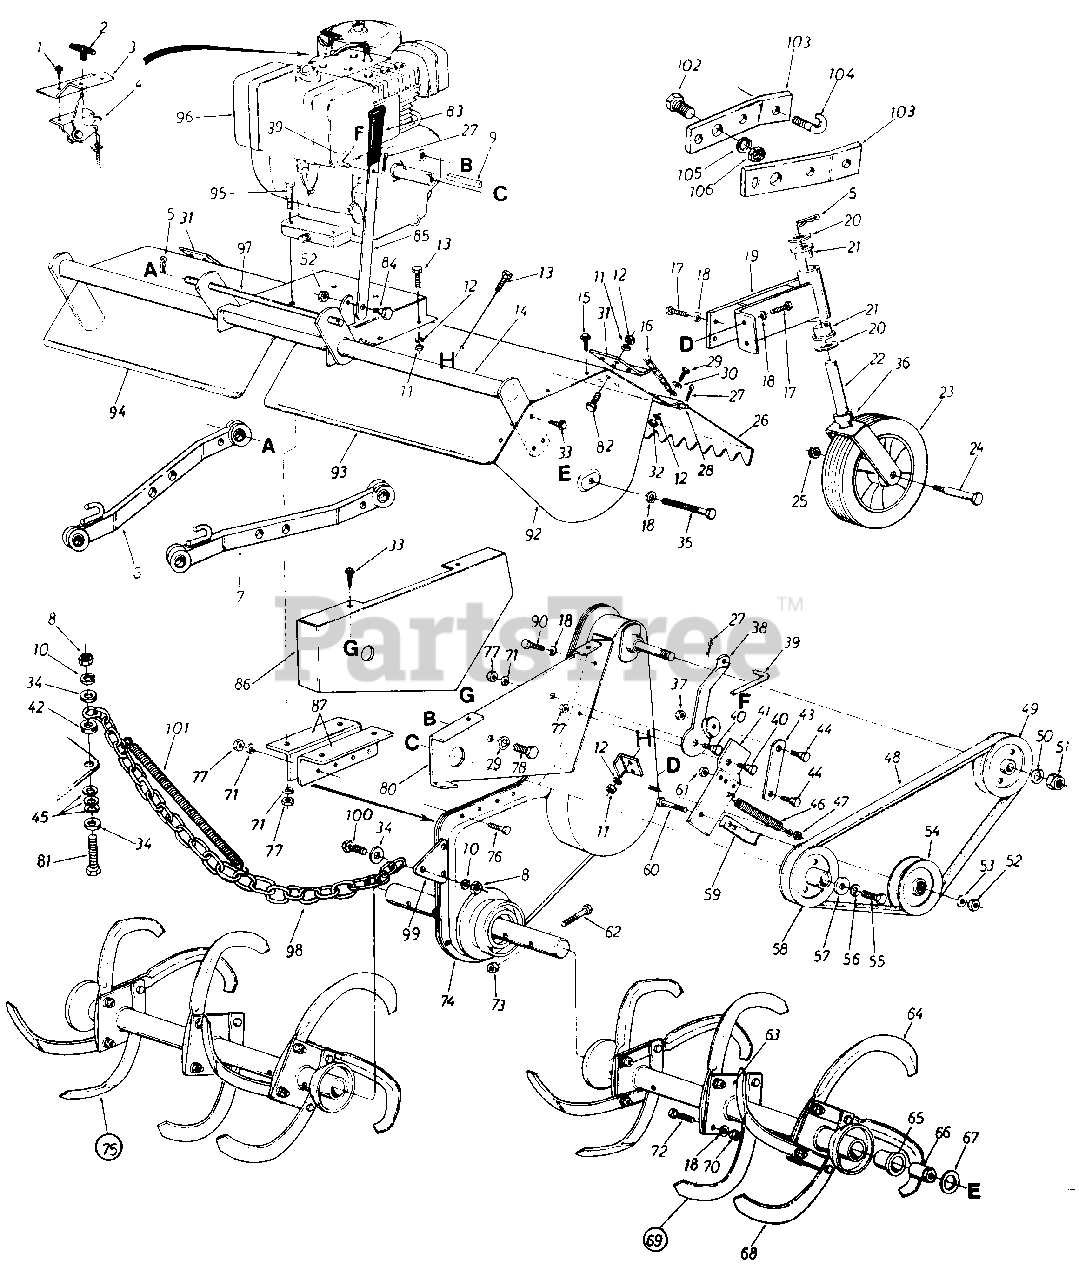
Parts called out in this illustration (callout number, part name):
1	Hex Wash. Hd. Self-Tap Scr. #8 x .50" Lg.
2	Throttle Control Knob
3	Throttle Control Bracket
4	Throttle Control Ass'y. Comp.
5	Internal Cotter Pin
6	Draft Bar Ass'y. R.H.
7	Draft Bar Ass'y. L.H.
8	Hex Nut 3/8-24 Thd.
9	Sq Key 1/4" X 1/4" X 2.00" Lg.
10	L-Wash. 3/8" I.D.
11	Hex Nut 1/4-28 Thd.
12	L-Wash. 1/4" I.D.
13	Hex Bolt 1/4-28 X .62" Lg.
16	#2 Dog Chain x 20" Lg.
17	Hex Wash. Hd. Self-Tap Scr. 3/8-24 x .75" Lg.
18	L-Wash. 3/8" I.D.
21	Flange Bearing 3/4" I.D. x 1.00" O.D.
24	Shoulder Bolt .623" I.D. x 3.62" Lg.
25	Hex Cent. L-Nut 7/16-14 Thd.
28	L.H Flap Rod
29	Hex Bolt 1/4-20 x .62" Lg.
30	Fl-Wash. 1/4" I.D.
33	Hex Wash. Hd. Self-Tap Scr. 1/4" X .62" Lg.
34	Fl-Wash. .385n l.D. x 1.0" O.D. x .135 Thk.
35	Hex Bolt 3/8-16 x 1.25n Lg.
36	Spacer.752" I.D. x 1.25n
37	Hex Cent. L-Nut 5/16-18 Thd.
40	Shoulder Bolt 7/16" Dia. x 1.75" Lg.
45	Fl-Wash. .406" I.D. x .74" O.D. x .063 Thk.
46	Extension Spring .62" O.D. x 6.12" Lg.
47	Hex Crown Nut 3/8-24 Thd.
48	"V"-Belt 1/2" x 43" Lg . (Kevlar)
49	1/2" "V"-Pulley 4.75" O.D. x .625" Bore
50	L-Wash. 5/8" I.D.
51	Hex Ins. L-Nut 5/8-18 Thd.
52	Hex Cent. L-Nut 3/8-16 Thd.
53	Fl-Wash. 3/8" I.D.
54	Idler Pulley 4.0" O.D.
55	Hex Bolt
56	L-Wash. 7/16" I.D.
57	Fl-Wash. 7/16" I.D. x 1.38" O.D.
58	1/2" "V"-Pulley .475" O.D. x 1.00" Bore
61	Hex Cent. L-Nut 5/16-18 Thd.
62	Hex Bolt 7/16-14 x 2.00" Lg.
66	Spacer
67	Thrust Wash. 1/2" I.D. x 1.55" O.D.
71	L-Wash. 5/16" I.D.
72	Hex Bolt 3/8-24 x 1.5n Lg.
73	Hex Cent. L-Nut 7/16-14 Thd.
77	Hex Nut 5/16-18 Thd.
78	Hex Bolt 1/2-20 x .88" Lg. (Grade 5)
79	L-Wash. 1/2" I.D.
80	Clutch Support Bracket
81	Hex Bolt 3/8-24 x 1.75" Lg.
82	Hex Bolt 1/4-28 x 75" Lg.
83	Plastic Grip
84	Shoulder Bolt .498 Dia. x .212 Lg.
85	Clutch Handle
96	8 H.P. Engine
97	Tiller Mounting Shaft 16" Lg.
98	Chain 23" Lg.
99	Tiller Mounting Bracket
100	Hex Bolt 3/8-24 x 1.25" Lg.
101	Extension Spring
102	Hex Bolt 5/8-18 x 1.62" Special
103	Drag Link Extension
104	Hitch Chain Hook
105	L-Wash. 5/8" I.D.
106	Hex Jam Nut 5/8-18 Thd.
